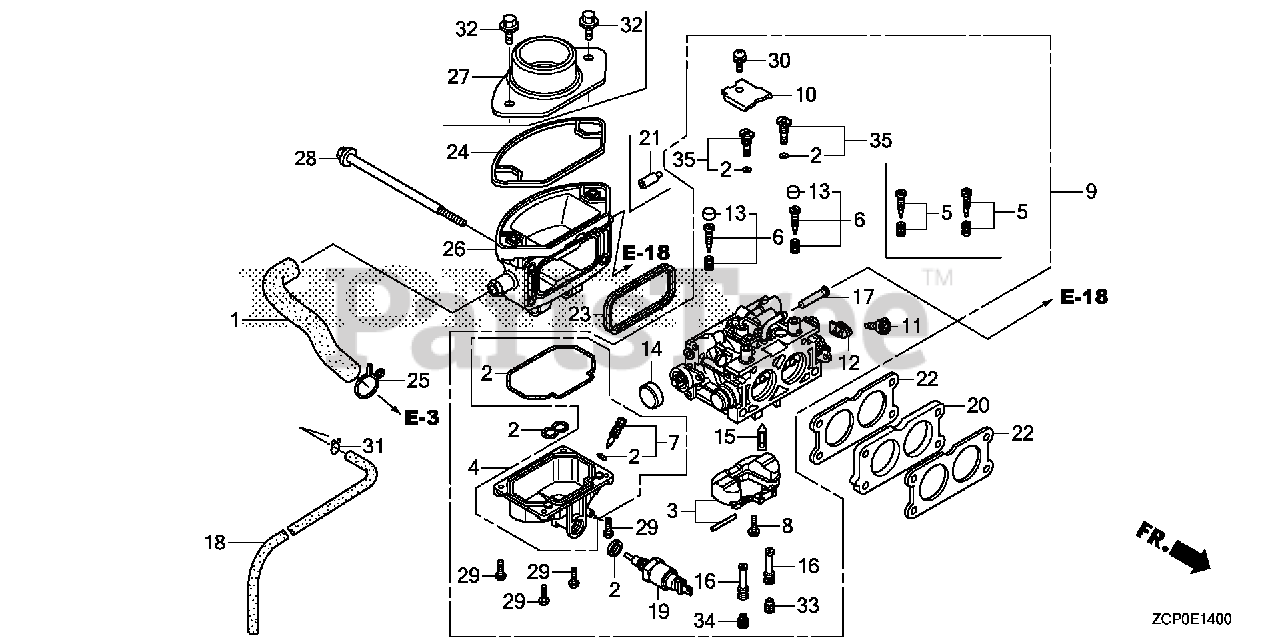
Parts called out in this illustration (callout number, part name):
1	TUBE, BREATHER
2	GASKET SET
4	CHAMBER SET, FLOAT
7	SCREW SET, DRAIN
8	SCREW, FLOAT
9	CARBURETOR ASSY. (BK06C B)
11	SCREW, THROTTLE STOP
12	ARM, THROTTLE LINKAGE
13	CAP, ADJUSTING SCREW
14	CAP, CHOKE DUST
15	VALVE, FLOAT
16	NOZZLE, MAIN
17	SCREEN, FUEL STRAINER
18	TUBE, DRAIN
19	VALVE ASSY., SOLENOID
20	INSULATOR, CARBURETOR
22	GASKET, CARBURETOR
23	GASKET, AIR CLEANER
24	SEAL, AIR CLEANER HOUSING
25	CLIP, BREATHER TUBE
26	ELBOW, AIR CLEANER
27	JOINT, CONNECTING TUBE
28	BOLT, FLANGE (6X106)
29	SCREW, PAN (4X12)
30	SCREW-WASHER (5X10)
31	CLIP, TUBE (B8)
32	BOLT, FLANGE (6X12)
33	JET, MAIN (#100)
33	JET, MAIN (#105)
33	JET, MAIN (#112)
34	JET, MAIN (#100)
34	JET, MAIN (#105)
34	JET, MAIN (#112)
35	JET SET, PILOT (#40)
